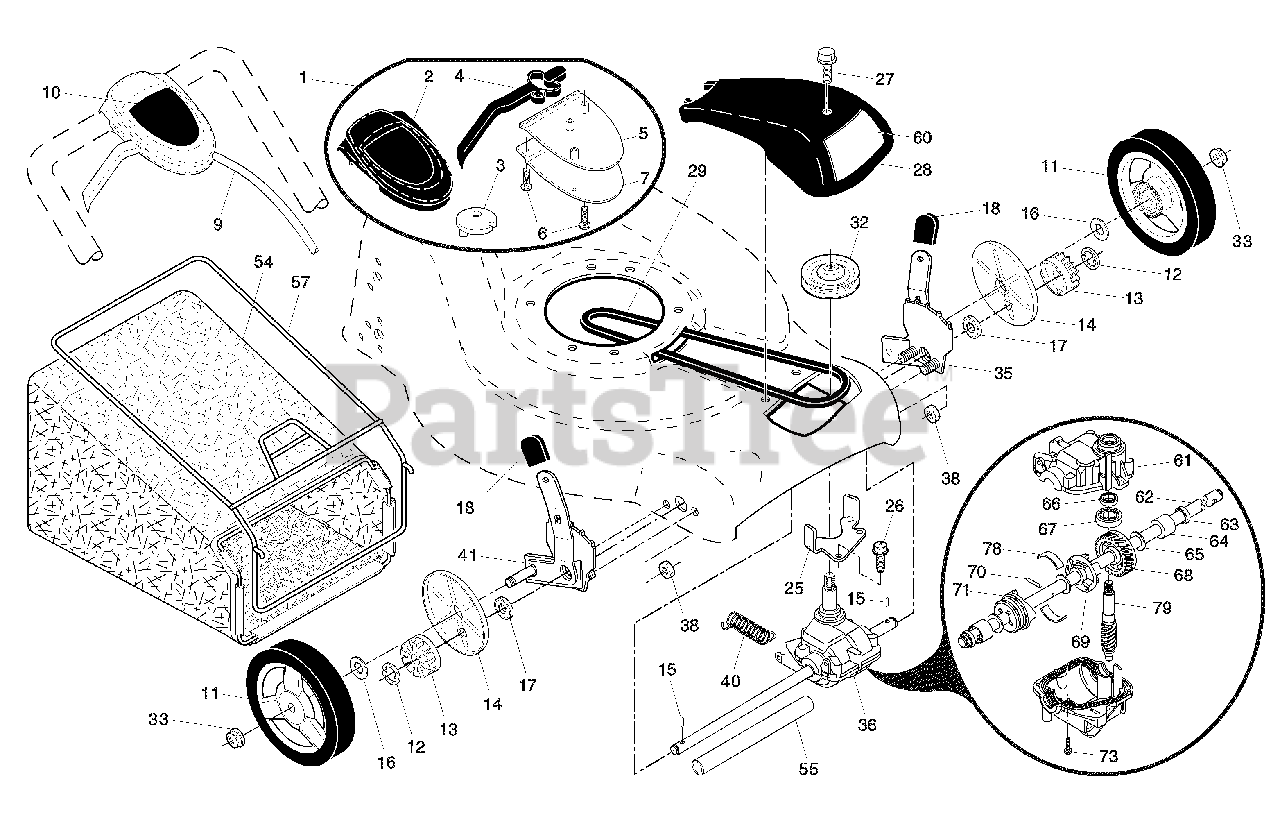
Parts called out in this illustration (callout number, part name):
1	Drive Control Assembly
2	Cover, Drive Control, Upper
4	Lever, Drive Control
5	Cover, Drive Control, Lower
7	Mounting Bracket, Drive Control
9	Cable, Drive Control
10	Decal, Drive Control
11	Wheel & Tire Assembly
14	Dust Cover
15	Pawl, Drive
16	Washer 1/2 x 1-1/2 x .134
17	Bearing, Wheel Adjuster
18	Selector Knob
25	Belt Keeper
26	Screw, Hi-Lo Thread
27	Pan Head Tapping Screw #10-24 x 2-3/4
28	Drive Cover
32	Drive Pulley
33	Locknut, Hex
35	Kit, Wheel Adjuster, LH
36	Gearcase Assembly, Complete
38	Locknut, Hex 1/4-20
41	Kit, Wheel Adjuster, RH
54	Grassbag Assembly
55	Driveshaft Cover
57	Frame, Grassbag
60	Decal, Drive Cover
61	Case, Upper
62	Shaft, Output
63	Seal, Output Shaft
66	Seal, Worm Shaft
67	Bearing, Ball
68	Gear, 28 Teeth
69	Fixed Dog Clutch
71	Movable Dog Clutch
73	Screw, Case
74	Case, Lower
79	Shaft, Worm
